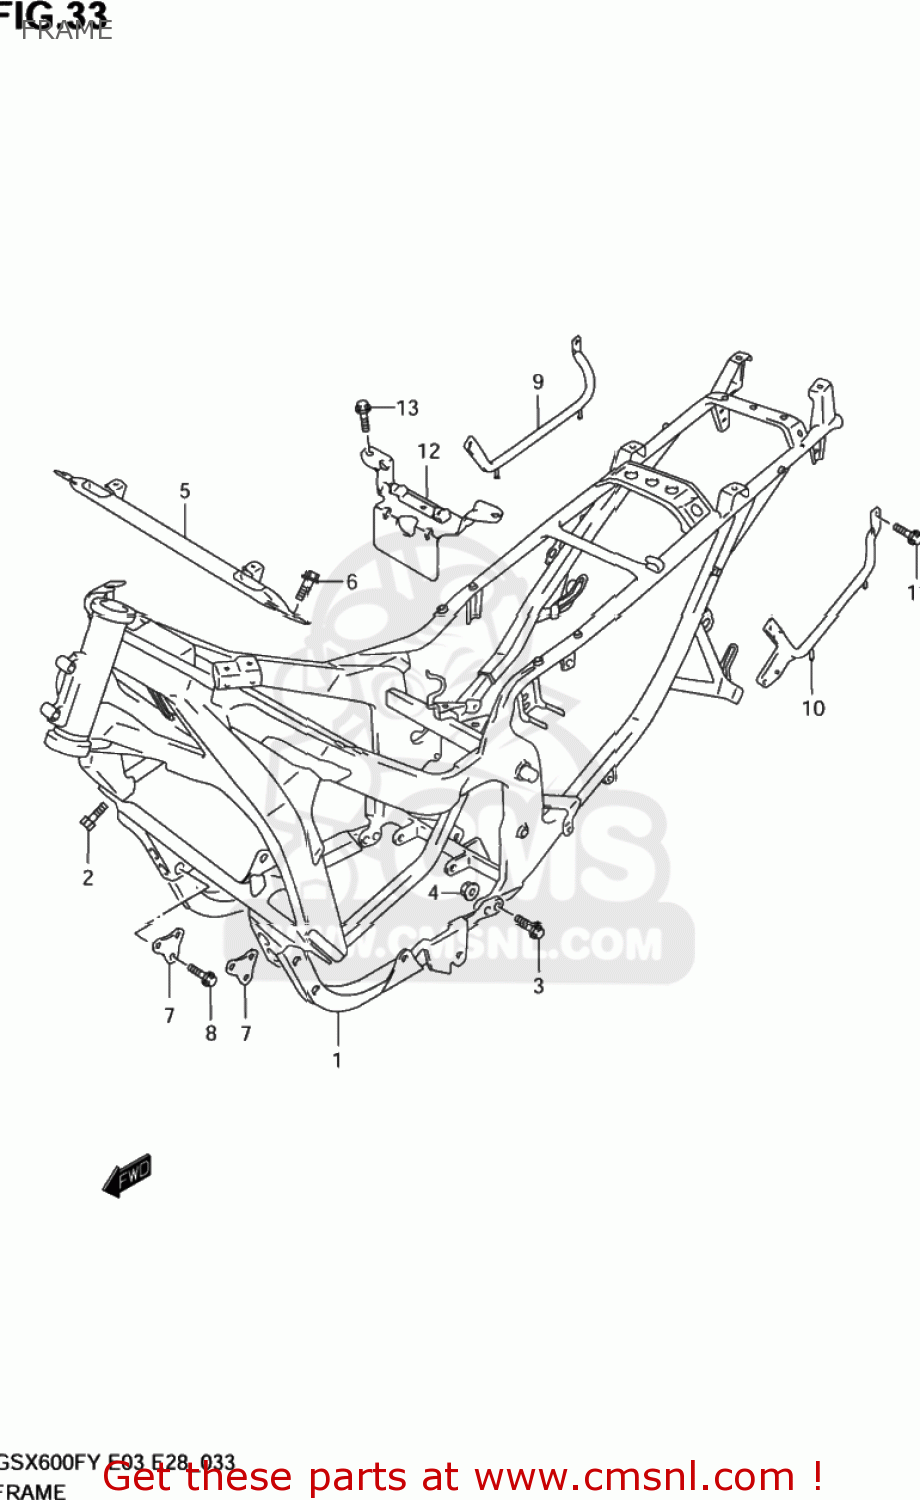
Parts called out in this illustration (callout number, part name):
1	FRAME(BLACK)
2	BOLT
3	BOLT
4	NUT
5	TUBE,FRAME BRIDGE NO.2
6	BOLT(8X20)
7	PLATE,ENG MTG NO.1
8	BOLT, UPPER
9	GRIP,RR,R
10	GRIP,RR,L
11	BOLT
12	PLATE COMP,ELECTRIC PARTS
13	BOLT
